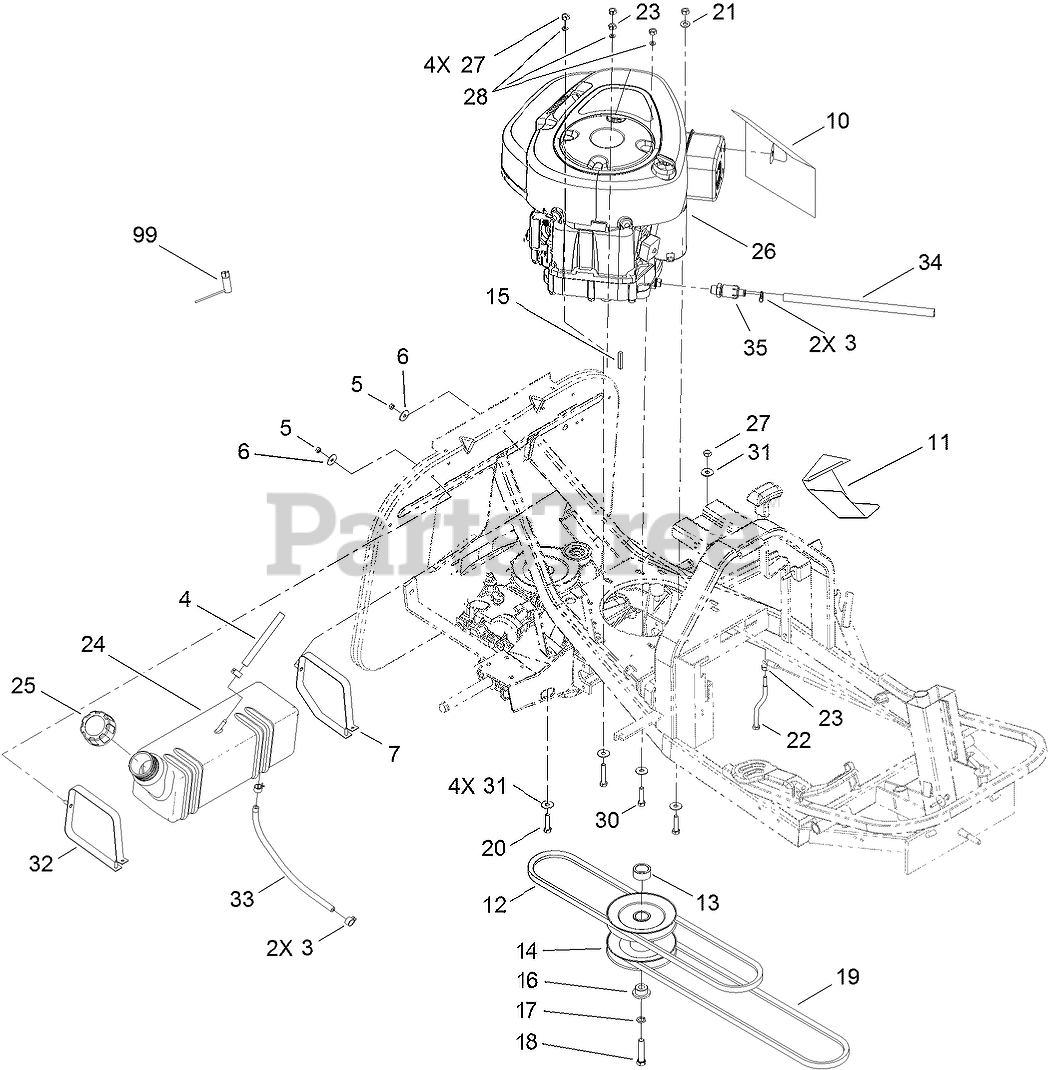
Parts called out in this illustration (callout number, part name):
3	CLAMP-TUBE
4	Hose-Fuel
5	NUT-LOCK
6	Washer-Flat
7	STRAP-FUEL TANK, LEFT
10	SHIELD-MUFFLER
11	DEFLECTOR-EXHAUST
13	Spacer
14	PULLEY-ENGINE, HYDRO
15	KEY-SQUARE
16	Spacer
17	Washer-Lock
18	SCREW-HH
19	BELT-DECK
20	SCREW-HH
21	WASHER-PLAIN
22	Guide-Belt
23	NUT-HEX
24	TANK-FUEL
25	GAS CAP ASM
27	NUT-LOCK
28	WASHER-FLAT
30	Screw-HH
31	Washer-Flat
32	STRAP-FUEL TANK, RIGHT
33	Hose-Fuel
34	TUBE-DRAIN, OIL
35	VALVE-DRAIN, OIL
